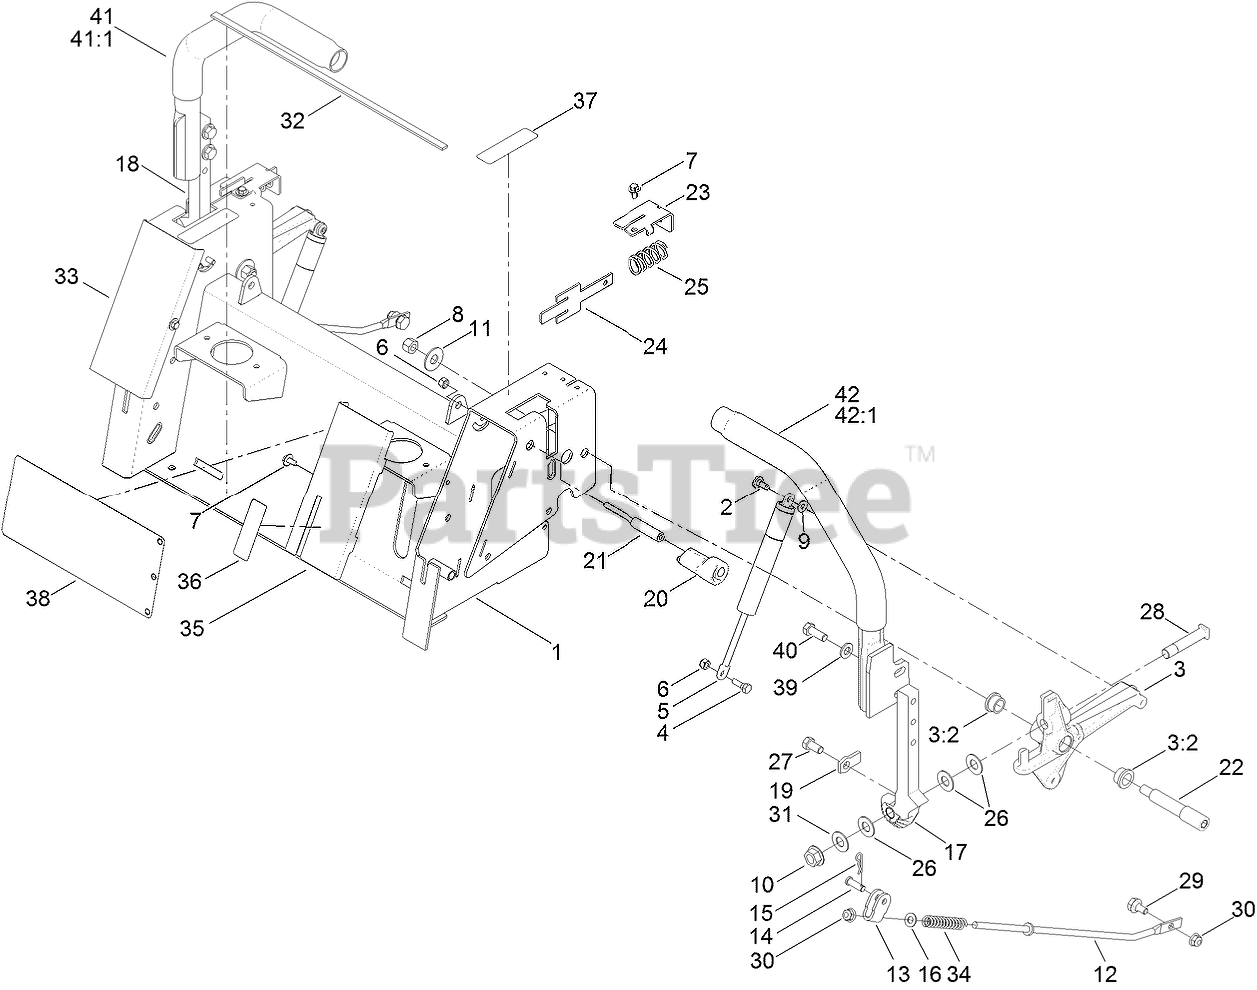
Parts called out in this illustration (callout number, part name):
1	BOX-CONTROL
2	SCREW-SHOULDER
3	ACTIVATOR ARM ASM
3:2	BUSHING
4	BOLT-SHOULDER
5	DAMPER-CONTROL, MOTION
6	NUT-LOCK, NI
7	SCREW-HHFTF
8	NUT-LOCK, NI
9	WASHER
10	NUT-HF
11	WASHER-FLAT
12	ROD-CONTROL
13	BRACKET-CONTROL
14	PIN-CLEVIS
15	PIN-COTTER
16	WASHER-PLAIN
17	ARM-ACTUATOR, LH
18	ARM-ACTUATOR, RH
19	TAB-STOP
20	ECCENTRIC
21	SCREW-ECCENTRIC
22	BOLT-SHOULDER
23	BRACKET-RETURN
24	PLATE-RETURN
25	SPRING-COMPRESSION
26	WASHER-PIVOT
27	SCREW-HH
28	BOLT-SHOULDER
29	BOLT-SHOULDER
30	NUT-HF, NI
31	WASHER-TEFLON
32	STRIP-VIBRATION, ANTI
33	COVER-CONTROL, RH
34	SPRING-RETURN, NEUTRAL
35	COVER-CONTROL, LH
36	DECAL-BRAKE, PARKING
37	DECAL-CONTROL, MOTION
39	WASHER-FLAT
40	SCREW-HH
41	RH LEVER/GRIP ASM
41:1	Grip-Control, Motion
42	LH LEVER/GRIP ASM
42:1	Grip-Control, Motion
